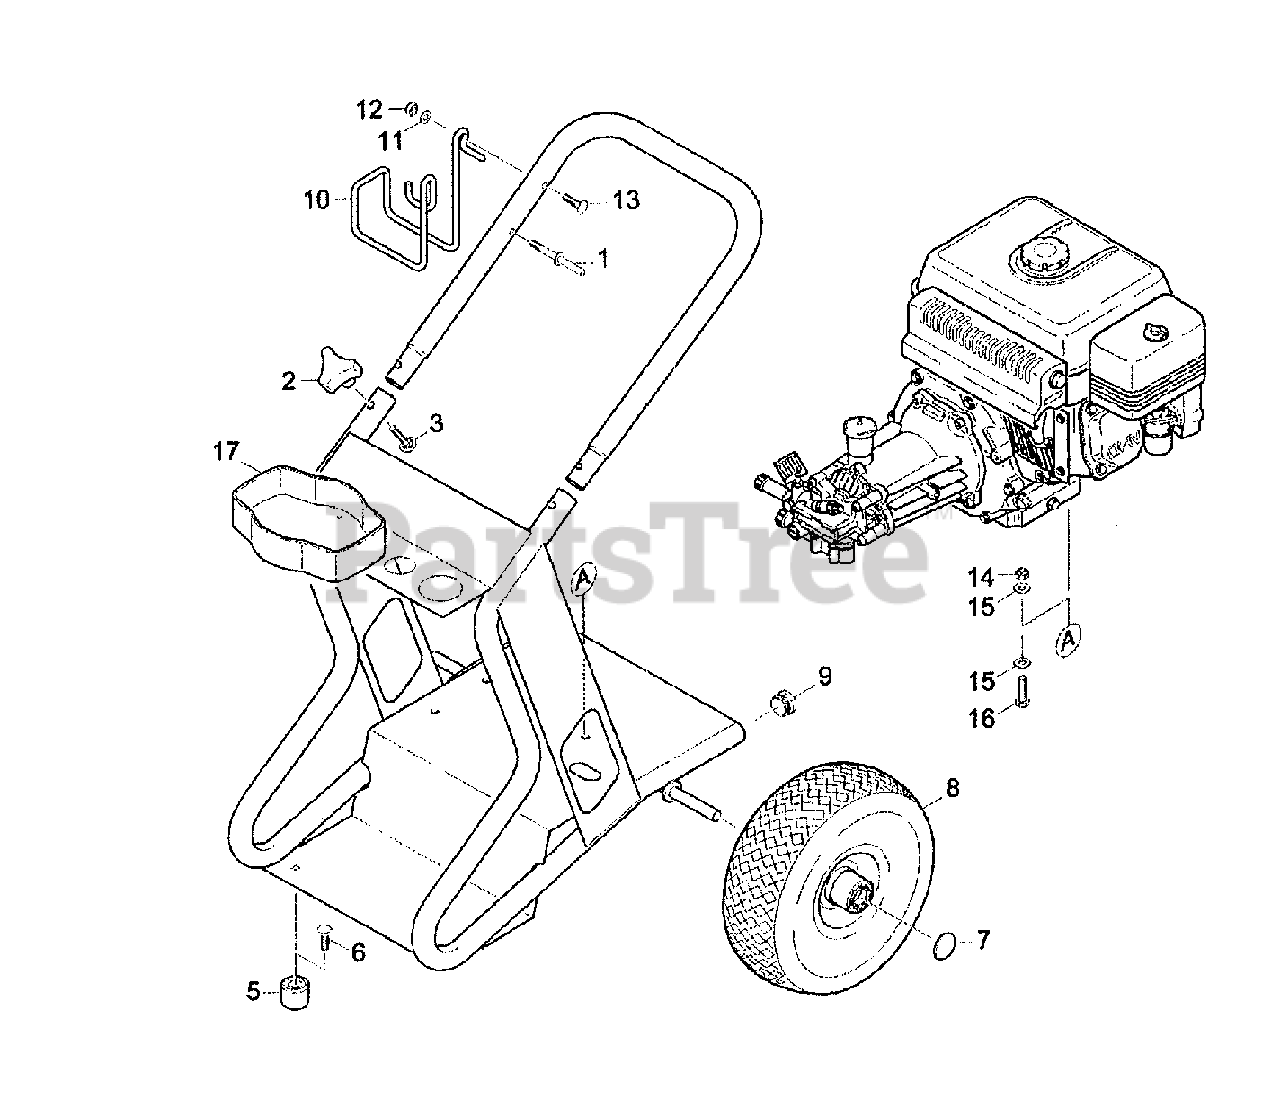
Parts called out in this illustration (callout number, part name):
1	Bolt 5/16"-18 x 1.75"
2	Control Knob
3	Screw 5/16"-18 x1.5"
5	Rubber Bumper
6	Bolt 5/16"-18 x 3/4"
8	Wheel 10" x 3.5"
13	Screw 5/16"-18 x 1.75"
14	Nut 3/8"-16
15	Washer 3/8"
16	Screw 3/8"-16 x 2.0"
17	Tray, 1Gal. Chemical
